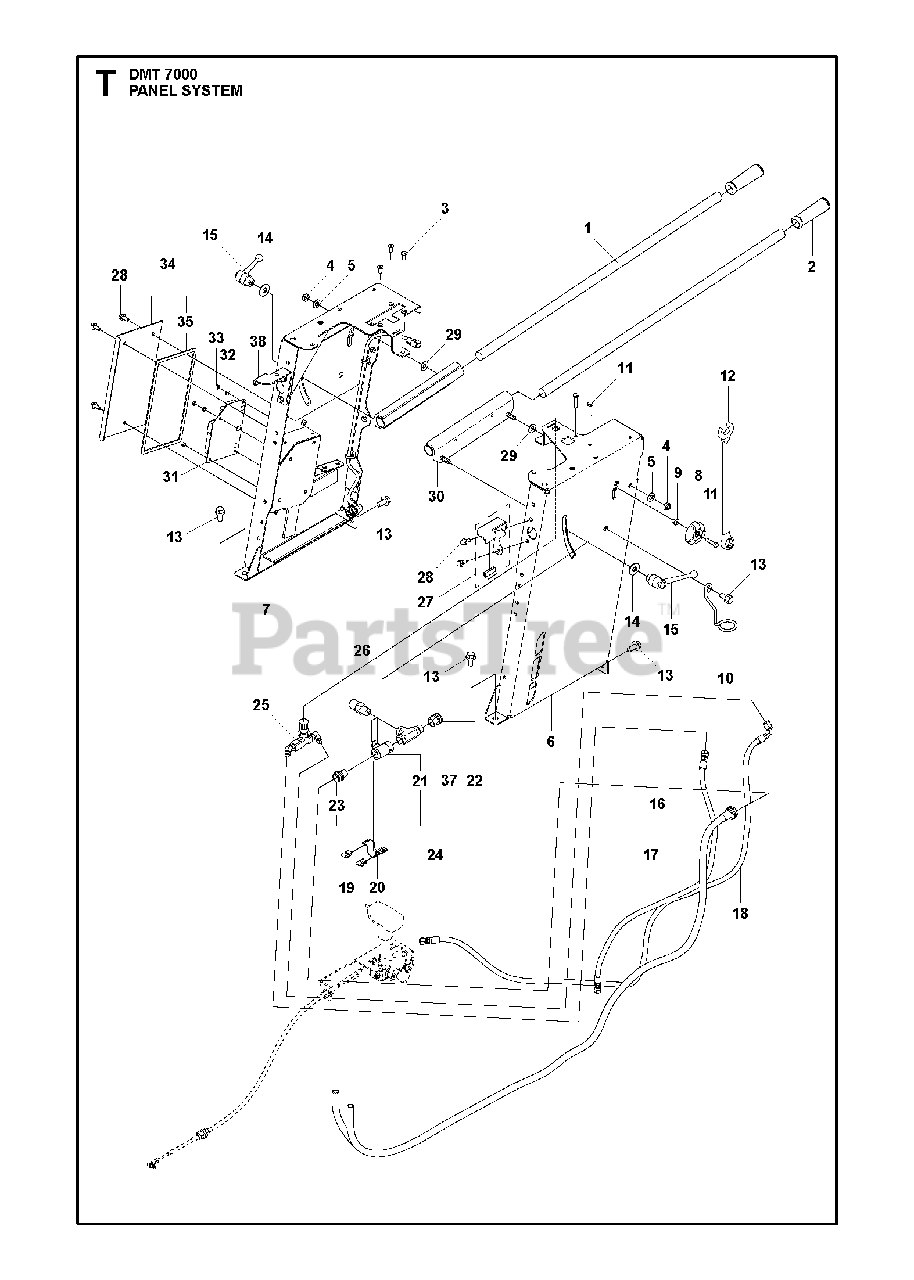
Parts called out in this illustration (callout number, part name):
5	WASHER
8	TURNING KNOB
9	HEXAGON NUT FLANGE
29	WASHER, FRICTION 1/2 X 1" OD
